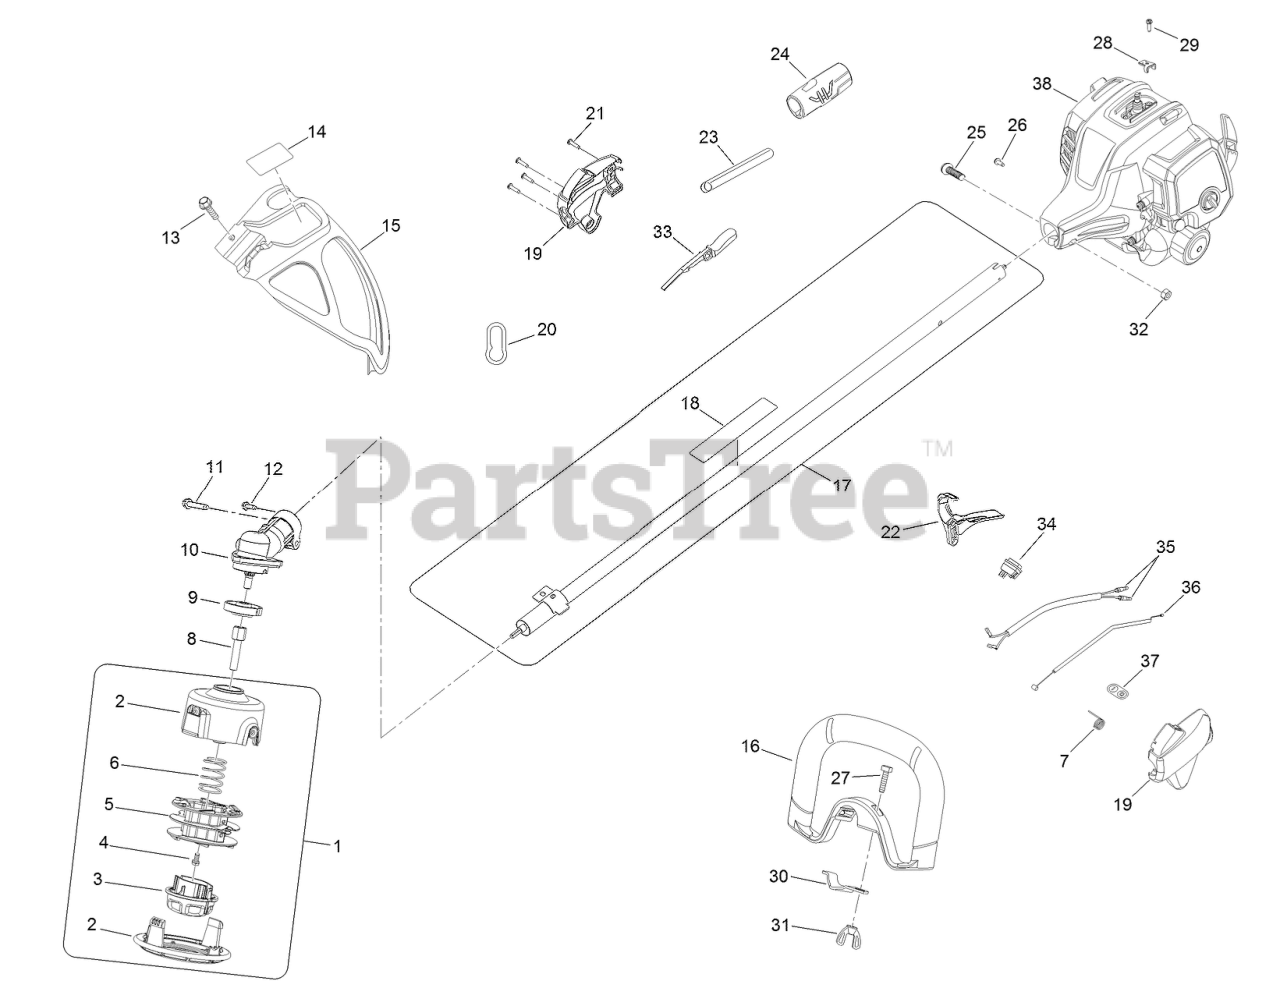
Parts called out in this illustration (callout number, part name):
3	KNOB-BUMP
5	SPOOL ASM
6	SPRING-COMPRESSION
7	SPRING-TRIGGER
8	ADAPTOR-HEAD SHAFT, TRIMMER
10	HEAD-GEAR
13	SCREW-HWH
14	DECAL-GRASS DEFLECTOR
15	GRASS DEFLECTOR ASM
16	HANDLE-SHAFT, UPPER
17	UPPER BOOM ASM
18	DECAL-WARNING
19	CONTROL HANDLE ASM
20	CLIP-STRAP, SHOULDER
22	TRIGGER
23	TUBE-CORRUGATED
24	GRIP-SHAFT, UPPER
28	CLAMP-CABLE, THROTTLE
30	CLAMP-HANDLE, UPPER SHAFT
31	NUT-WING
32	NUT-HEX
33	LOCK-TRIGGER
34	SWITCH-ON/OFF
36	CABLE-THROTTLE
37	LABEL-ON/STOP
38	Power Head ASM not serviced separately, for replacement parts see Power Head Components Assembly
